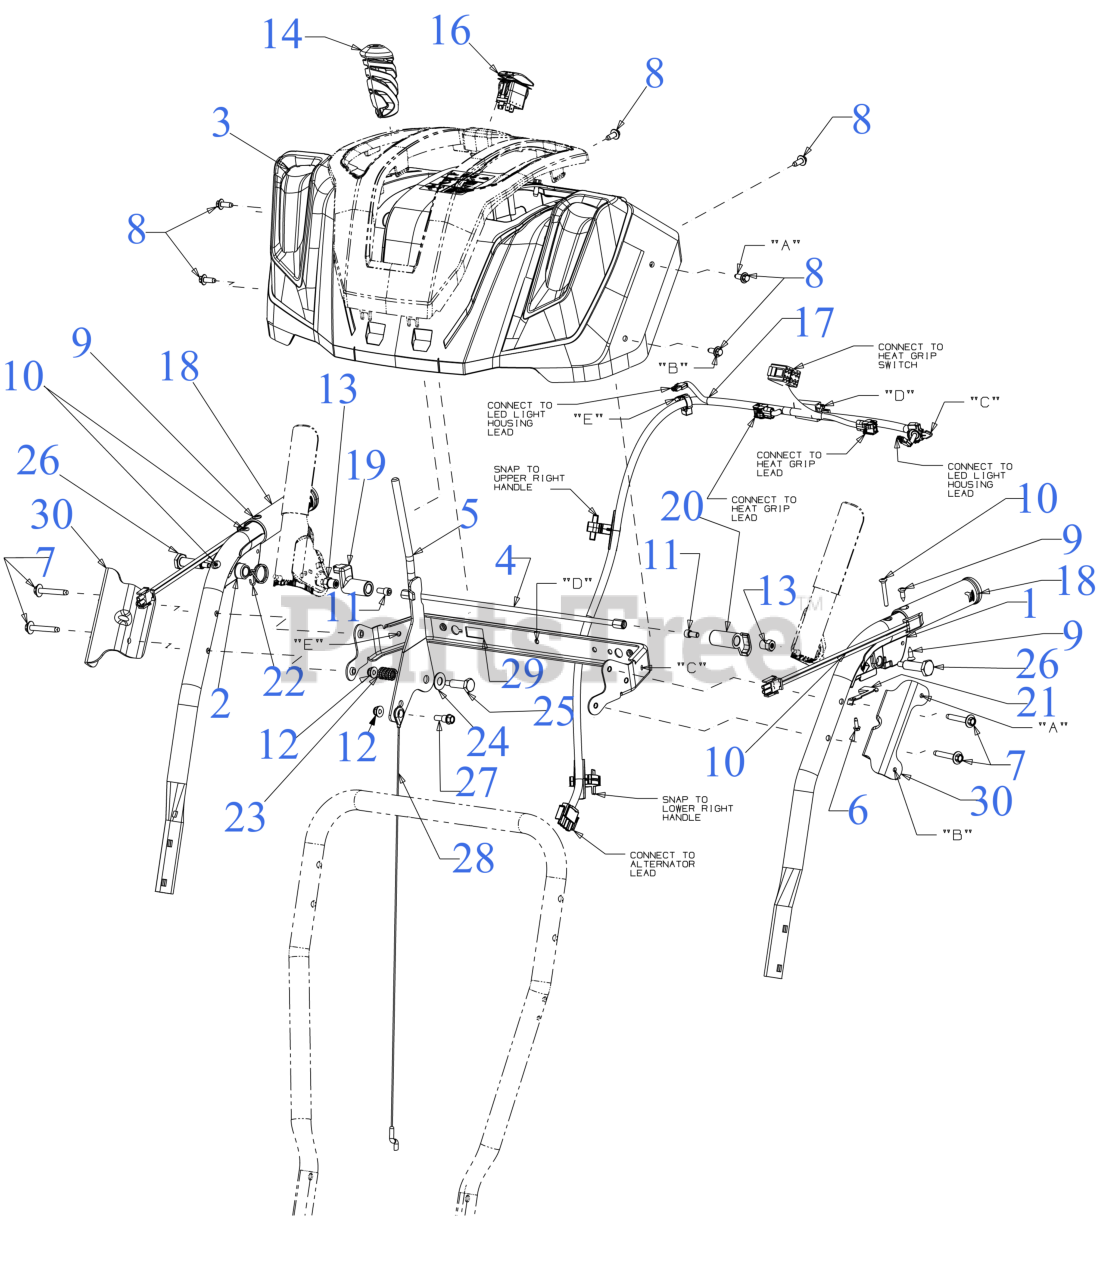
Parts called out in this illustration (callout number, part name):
1	CLUTCH LOCK HANDLE ASSEMBLY (LH)
2	CLUTCH LOCK HANDLE ASSEMBLY (RH)
3	Not Serviceable/ Components Only
3	LENS-LED SNOW
3	LED HEADLIGHT HARNESS ASSEMBLY
3	HANDLE PANEL ASSEMBLY
3	SCREW M6-1 x .625
3	SCREW 8/16X.500
6	SCREW #8-16 x .50
7	SCREW 1/4-20 x 1.625
8	SCREW M6-1 x .625
9	SCREW-AB #12-24 x .625
10	SCREW #10-24 x 1.375
11	SCREW 1/4-20 x .50
12	FLANGE LOCK NUT
13	HEX NUT W/PATCH
14	PTO HANDLE GRIP .355 ID
16	HEATED GRIP SWITCH
17	HARNESS (TWO HEADLIGHT)
18	HEATED GRIP
20	CLUTCH LOCK CAM
21	CLUTCH SPRING
22	TORSION SPRING
23	COMPRESSION SPRING
24	FLAT WASHER .401X.88
24	FLAT WASHER .38X.88
25	SHOULDER SCREW
26	SHOULDER SCREW .437 x 1.345 1/4-20
27	SHOULDER SCREW .342X.335X1/4-20
28	SELECTION CABLE
